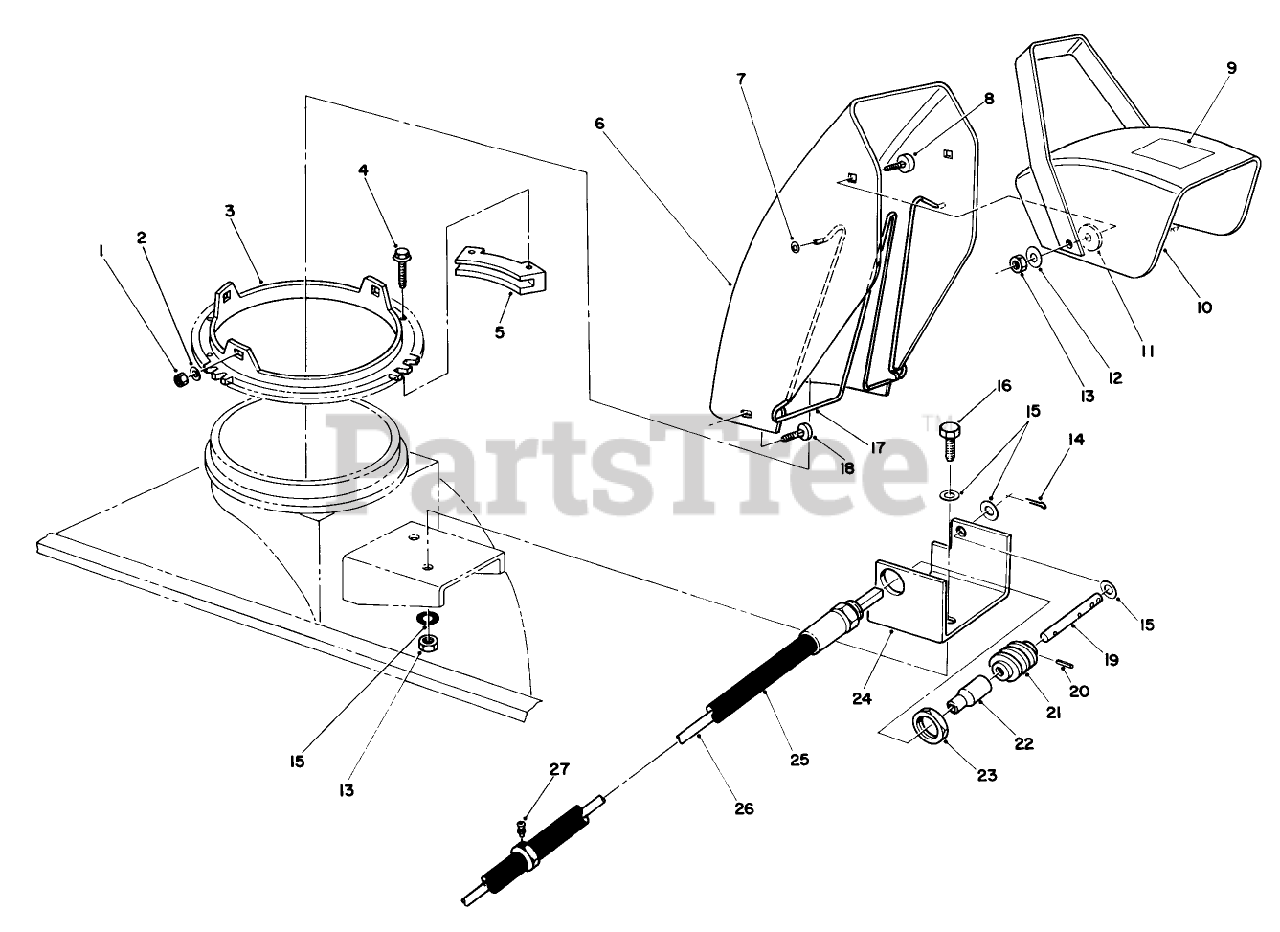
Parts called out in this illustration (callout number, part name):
1	NUT-LOCK, NI
2	WASHER-PLAIN
3	Screw
4	SCREW-SPECIAL
5	RETAINER-CHUTE
6	Chute-Upper
7	NUT-PUSH
8	SCREW-CARR
9	Decal-Discharge
10	Deflector
11	WASHER-RUBBER
12	WASHER-BELLEVILLE
13	Locknut
14	PIN-COTTER
15	WASHER-FLAT
16	SCREW-HH
17	CHUTE WIRE
18	SCREW-CARR
19	SHAFT-GEAR, WORM
20	PIN-SPRING
21	GEAR-WORM, CHUTE
22	COUPLER
23	LOCKNUT
24	WORM GEAR BRKT R
25	HOSE ASM
26	FLEX SHAFT
27	FITTING-GREASE
